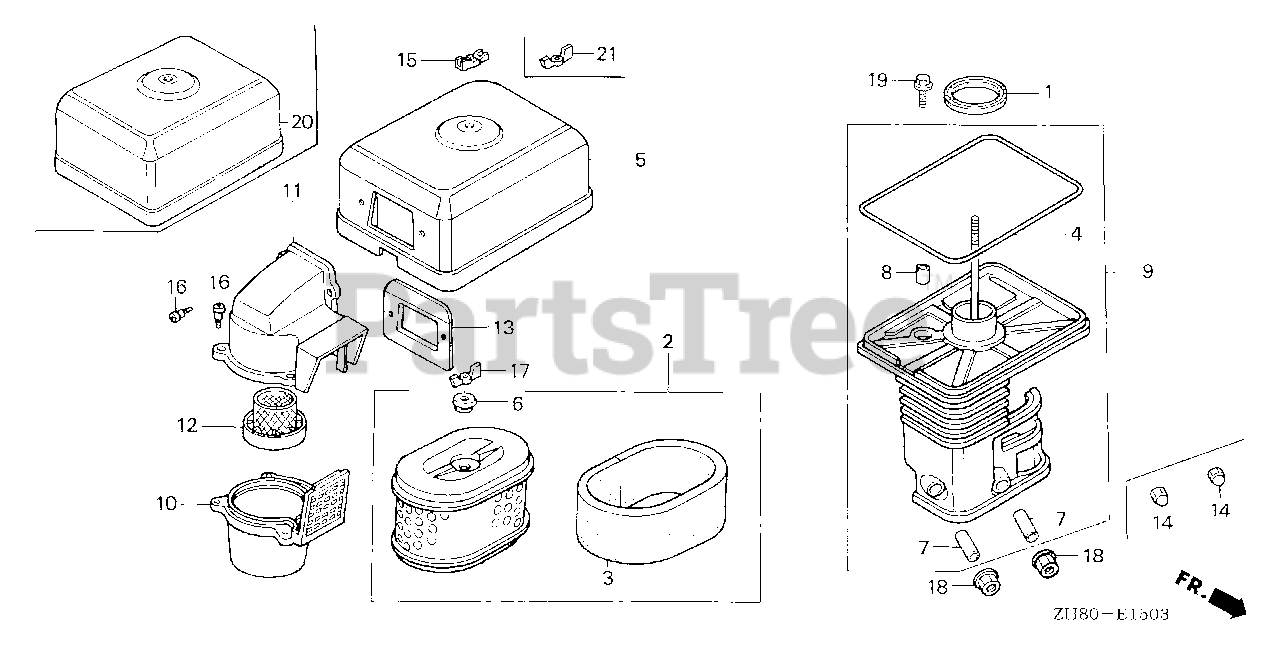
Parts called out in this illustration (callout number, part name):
1	GASKET, ELBOW
2	ELEMENT, AIR CLEANER (DUAL)
3	FILTER (OUTER)
4	GASKET, AIR CLEANER COVER
5	COVER, AIR CLEANER (DUAL)
6	GROMMET, AIR CLEANER
7	COLLAR, AIR CLEANER
8	COLLAR B, AIR CLEANER
9	ELBOW, AIR CLEANER
10	CASE, PRE AIR CLEANER
11	CAP, PRE AIR CLEANER
12	GUIDE, PRE AIR CLEANER
13	PLATE, PRE AIR CLEANER
14	NUT, CAP (6MM)
15	NUT, AIR CLEANER COVER (DACRO COATING)
15	WINGNUT (6MM) (BLACK)
16	BOLT, SPLASH GUARD
17	NUT, TOOL BOX SETTING
18	NUT, FLANGE (6MM)
19	BOLT, FLANGE (6X20)
21	NUT, TOOL BOX SETTING
